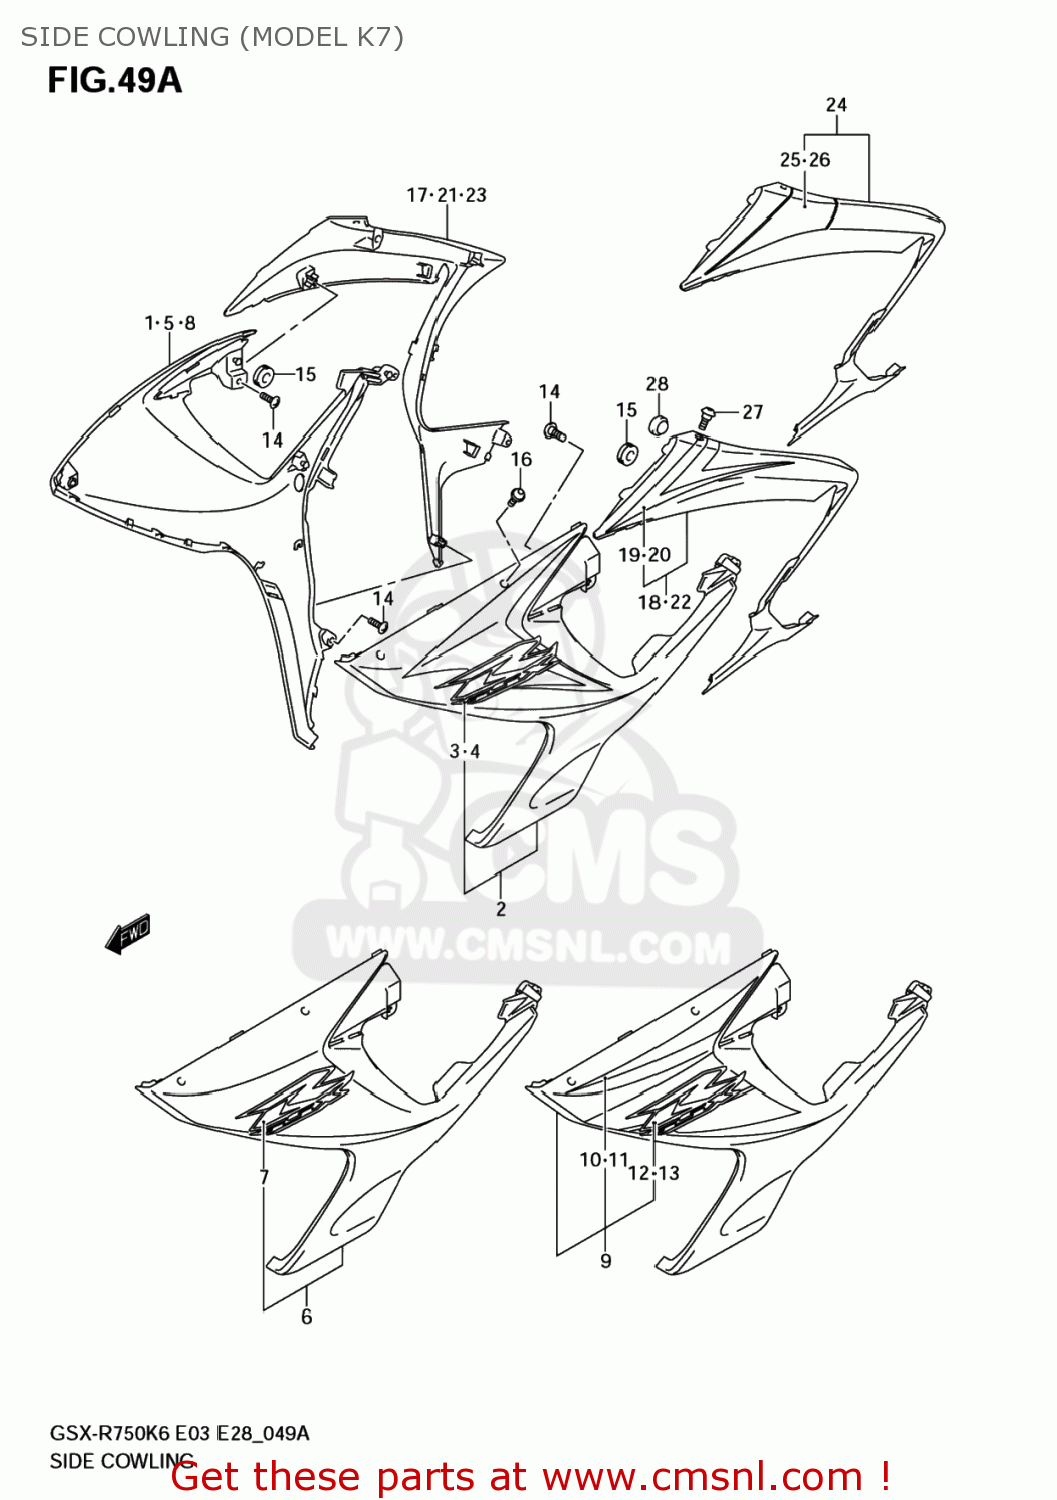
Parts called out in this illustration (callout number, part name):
1	COWLING,SIDE,R(BLUE)
2	COWLING,SIDE,L(BLUE)
3	TAPE,COWL SIDE,R
4	TAPE,COWL SIDE,L
5	COWLING,SIDE,R(BLACK)
6	COWLING,SIDE,L(BLACK)
7	EMBLEM,GSXR
8	COWLING,SIDE,R(BLUE)
9	COWLING,SIDE,L(BLUE)
10	TAPE,COWL SIDE UPR,R
11	TAPE,COWL SIDE UPR,L
12	TAPE,COWL SIDE,R
13	TAPE,COWL SIDE,L
14	SCREW
15	CUSHION
16	SCREW(5X13)
17	COVER,UNDER COWL,R(GRAY)
18	COVER,UNDER COWL,L(GRAY)
19	TAPE,COVER UNDER COWL,R
20	TAPE SET,COVER UNDER COWL,L
21	COVER,UNDER COWL,R
22	COVER,UNDER COWL,L
23	COVER,UNDER COWL,R(WHITE)
24	COVER,UNDER COWL,L(WHITE)
25	TAPE,COVER UNDER COWL,R
26	TAPE,COVER UNDER COWL,L
27	SCREW(5X16)
28	CUSHION
